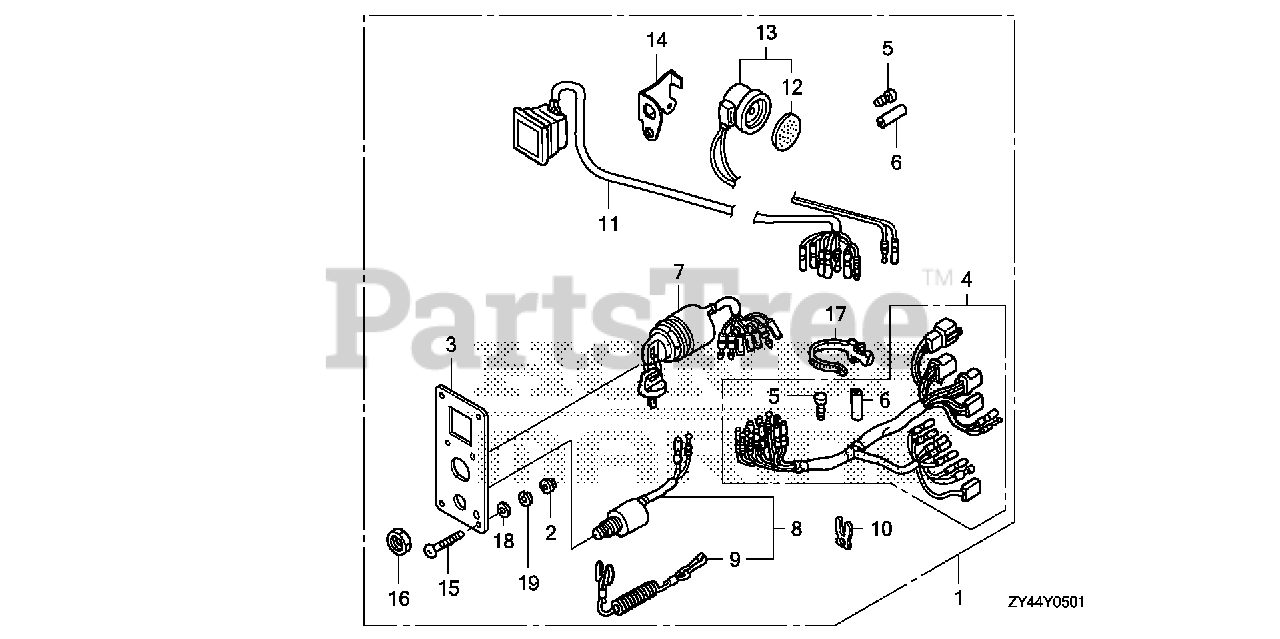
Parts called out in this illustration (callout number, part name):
1	PANEL KIT, SWITCH (4-LED)
2	NUT, FLANGE (5MM)
3	PANEL, CONTROL
4	HARNESS ASSY., SWITCH PANEL
5	PLUG, CONNECTOR (INNER)
6	PLUG, CONNECTOR (OUTER)
7	SWITCH ASSY., COMBINATION
8	SWITCH ASSY., EMERGENCY STOP
9	WIRE, EMERGENCY
10	CLIP, EMERGENCY LOCK
11	LAMP ASSY., INDICATION (4-LED)
12	PLATE, TURN SIGNAL BUZZER
13	BUZZER, WARNING
14	BRACKET, BUZZER
15	SCREW, PAN (5X40)
16	NUT, HEX. (16MM)
17	BAND, WIRE HARNESS (150MM) (NATURAL)
18	WASHER, PLAIN (5MM)
19	WASHER, SPRING (5MM)
